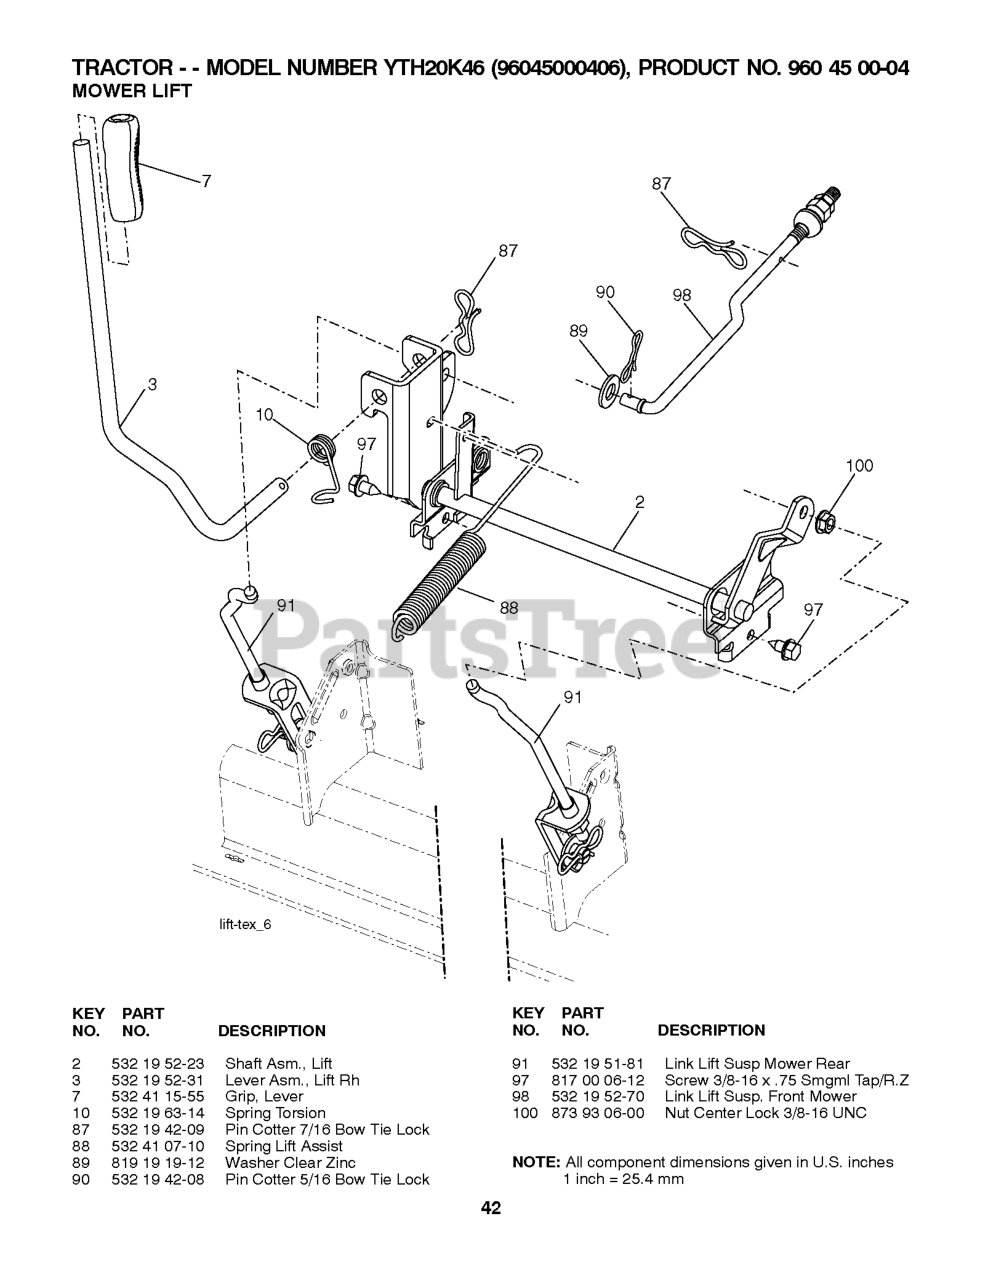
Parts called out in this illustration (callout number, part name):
2	SHAFT.ASM.LIFT.CROSS.H
3	LEVER.LIFT.HANDLE.LT
7	GRIP.HANDLE.LIFT.PVC.BLACK
10	SPRING.TORSION.LIFT.HANDLE
87	PIN.COTTER.7/16.BOW TI.
88	SPRING.LIFT.ASSIST
89	WASHER.CLEAR.ZINC
90	PIN.COTTER.5/16.BOW TI
91	LINK.ASM.LIFT.REAR
97	SCREW, 3/8-16X3/4
98	LINK.ASM.SUSP.FRONT.MW
100	LOCKNUT
